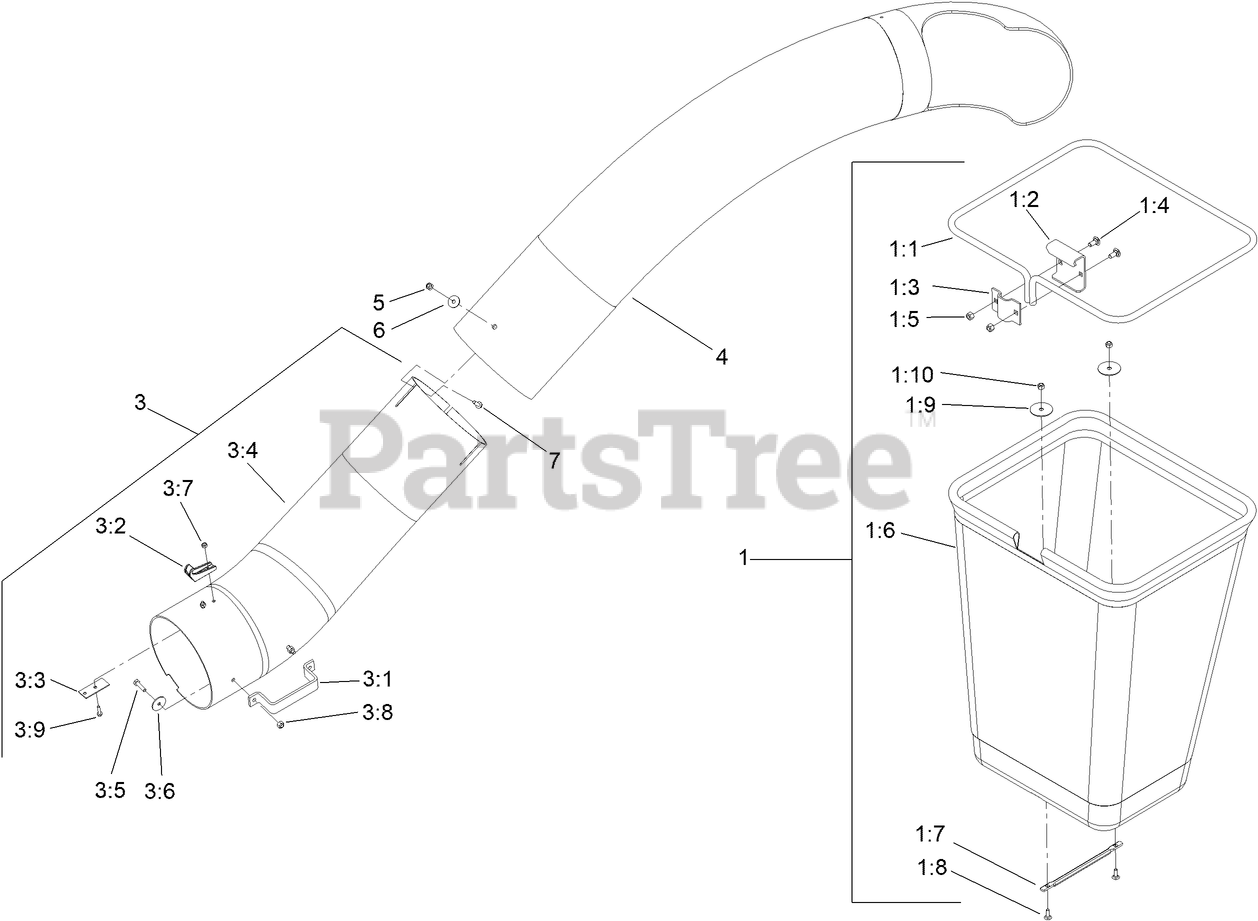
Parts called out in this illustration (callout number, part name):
1	BAG AND FRAME ASM
1:1	FRAME-BAG
1:2	HANGER-BAG
1:4	BOLT-CARR
1:5	NUT-LOCK, NI
1:7	HANDLE-BAG
1:8	BOLT-CARR
1:9	WASHER
1:10	NUT-LOCK, NI
3	LOWER TUBE ASM
3:2	LATCH-CATCH
3:3	PLATE-BACKING
3:4	TUBE-LOWER
3:5	SCREW-HH
3:6	WASHER-FLAT
3:7	NUT-LOCK, NI
3:8	NUT-LOCK, NI
3:9	SCREW-HWH
4	TUBE-UPPER
5	NUT-LOCK, NI
6	WASHER-FLAT
7	SCREW-HWH
